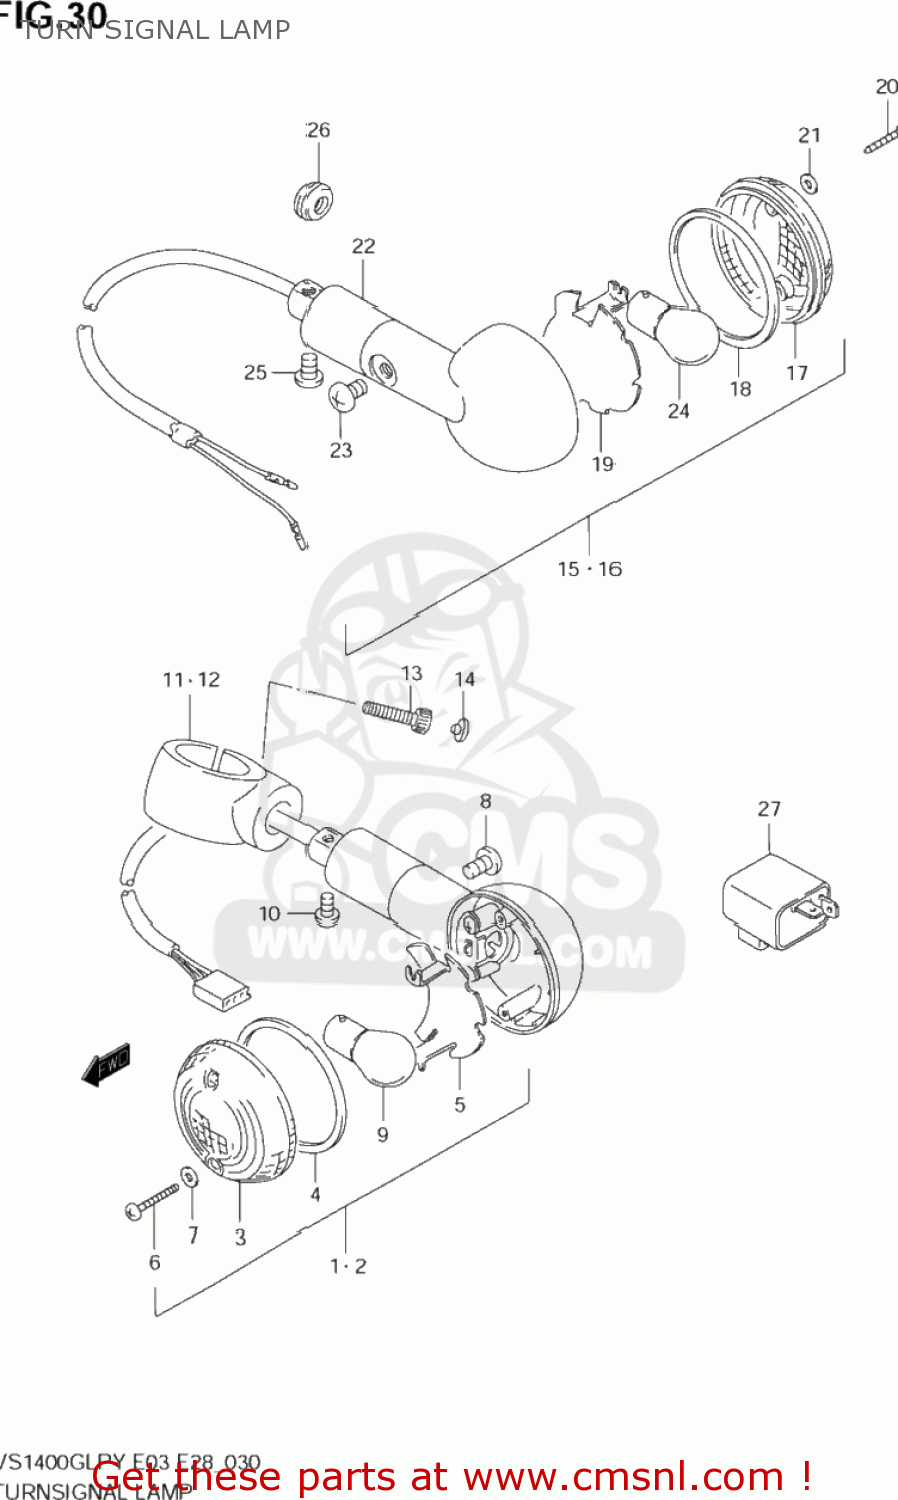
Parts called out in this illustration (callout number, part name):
1	LAMP ASSY,FR TURN SIGNAL,R
2	LAMP ASSY,FR TURN SIGNAL,L
3	LENS
4	GASKET (NAS)
5	REFLECTOR
6	SCREW
7	GASKET (NAS)
8	SCREW
9	BULB(12V21/5W,BF141-49642A)
10	SCREW
11	BRACKET,FR TURNSIGNAL LAMP,R
12	BRACKET,FR TURNSIGNAL LAMP,L
13	BOLT
14	CAP(OD:10)
15	LAMP ASSY,FR TURN SIGNAL
16	LAMP ASSY,FR TURN SIGNAL
17	LENS
18	GASKET (NAS)
19	REFRECTOR
20	SCREW
21	GASKET (NAS)
22	STAY,TURNSIGNAL LAMP
23	SCREW
24	BULB(12V21W)
25	SCREW
26	GROMMET
27	RELAY ASSY
